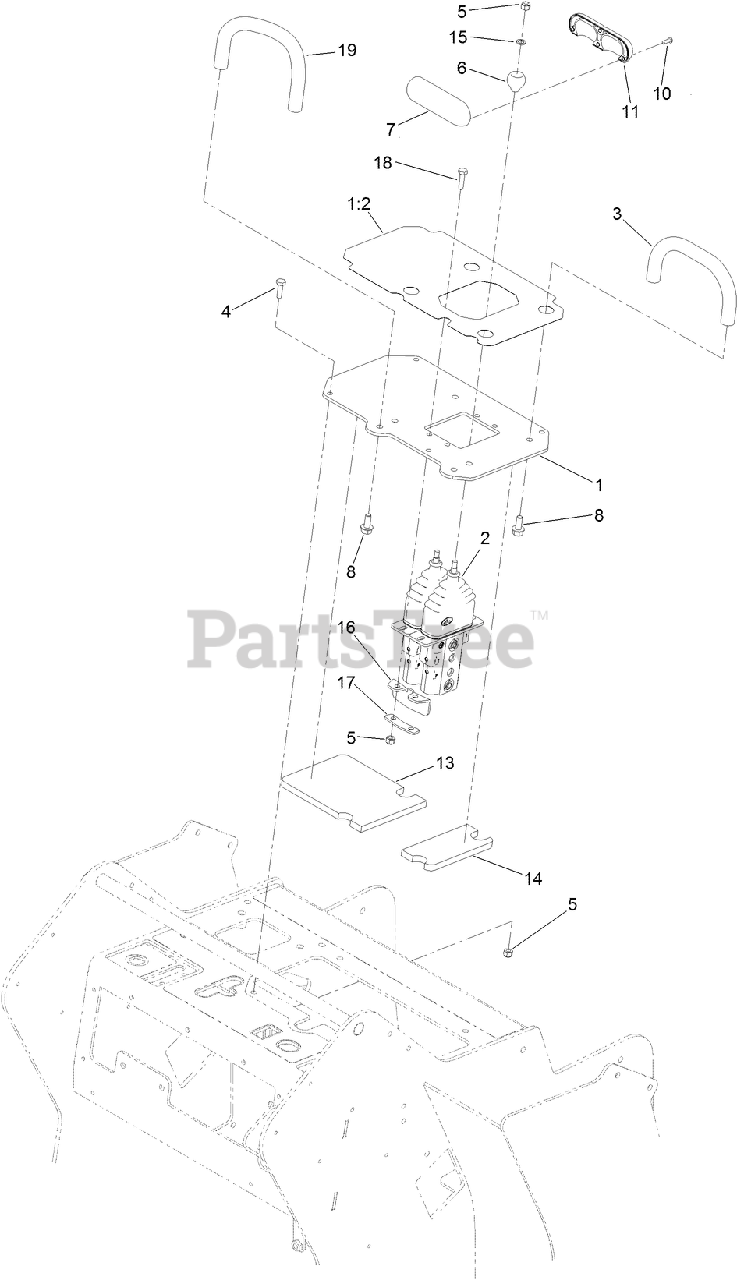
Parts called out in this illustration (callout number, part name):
1	PLATE-CONTROL
1:2	DECAL-CONTROL PANEL
2	VALVE-CONTROL
3	BAR-REFERENCE
4	SCREW-HH
5	NUT-LOCK, NI
6	BALL-TRACTION
7	HANDLE-CONTROL
8	SCREW-HH
10	SCREW
11	HANDLE-TRACTION
13	FOAM-SHIELD, HEAT
14	FOAM-SHIELD, HEAT
15	SPACER-BEARING
16	COVER-RUBBER
17	PLATE-CLAMP
18	SCREW-HH
19	BAR-REFERENCE
